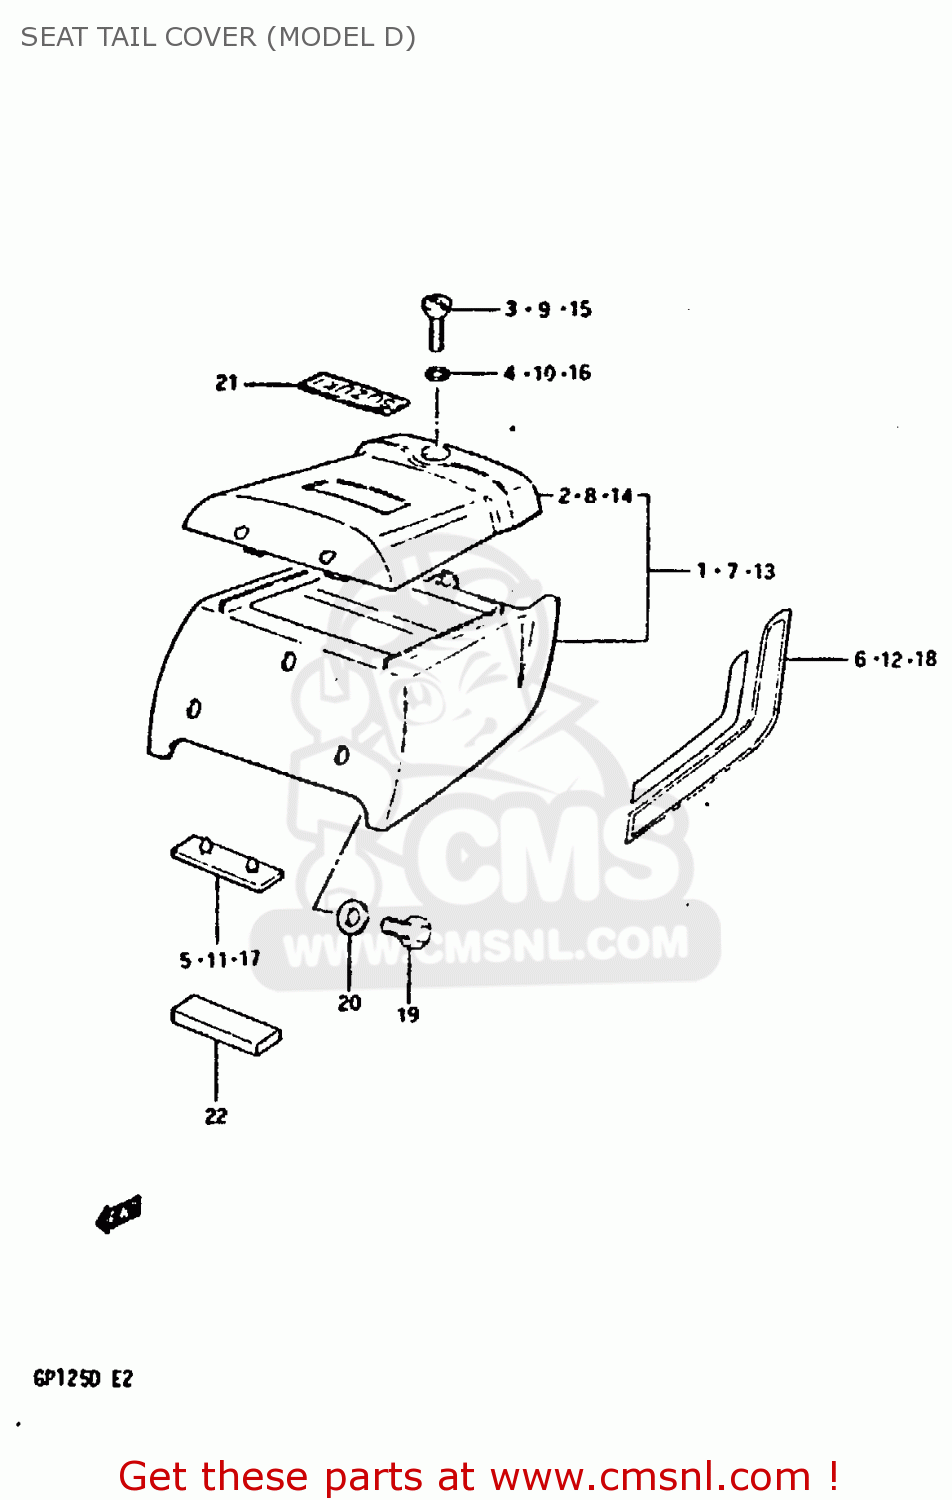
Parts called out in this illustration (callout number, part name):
1	COVER, SEAT TAIL
2	LID
3	KNOB,SEAT TAIL COVER
4	E RING
5	CUSHION
6	TAPE SET
7	COVER, SEAT TAIL
8	LID
9	KNOB,SEAT TAIL COVER
10	E RING
11	CUSHION
12	TAPE SET
13	COVER SET, TAIL (BLACK)
14	LID (BLACK)
15	KNOB,SEAT TAIL COVER
16	E RING
17	CUSHION
18	TAPE SET
19	BOLT, UPPER
20	WASHER
21	EMBLEM,CARB INSPECTION CAP
22	CUSHION,SEAT TAIL
